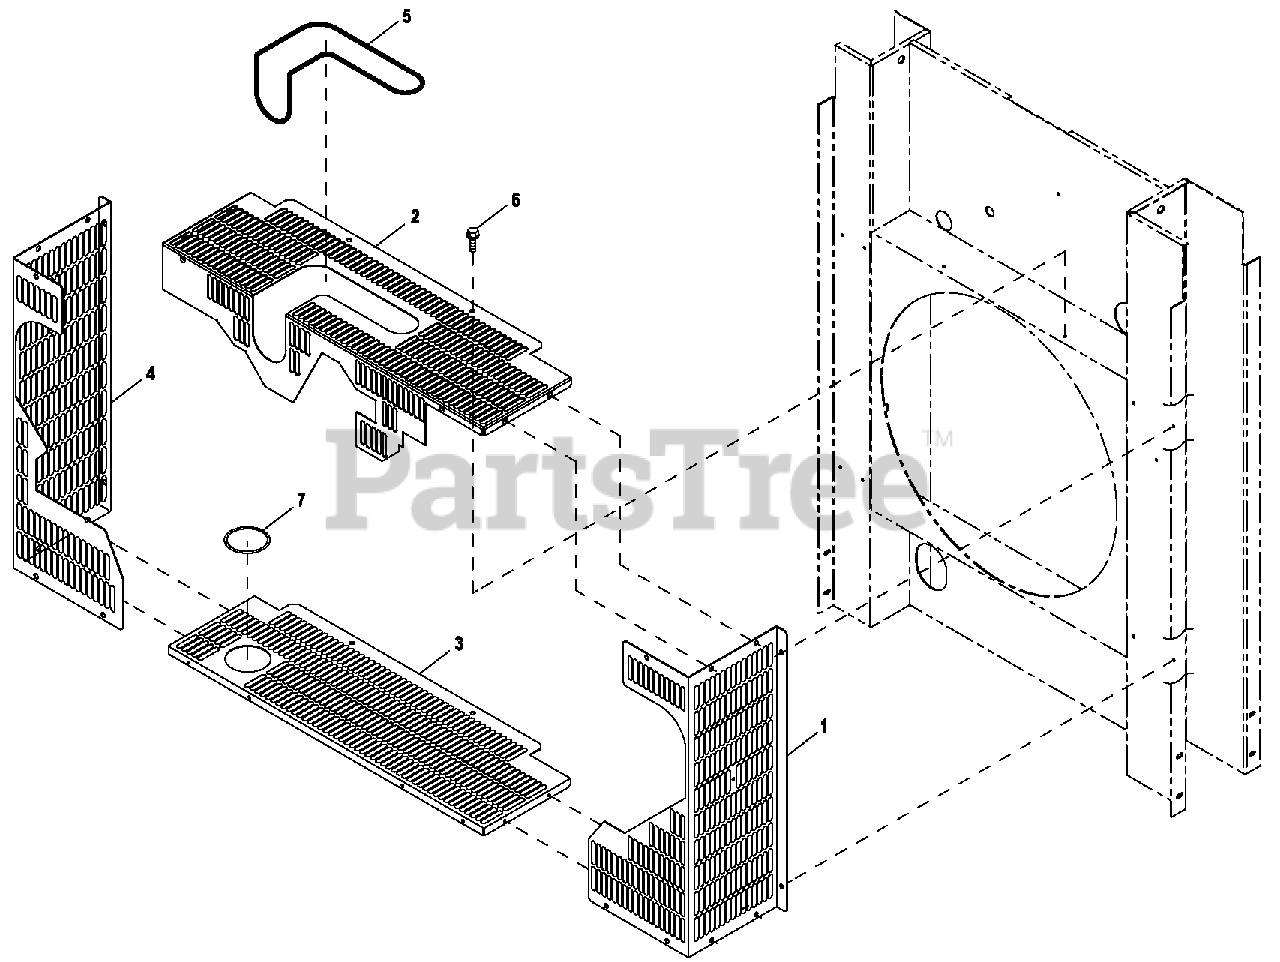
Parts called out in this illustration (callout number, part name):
1	GUARD BELT RIGHT HAND C3
2	BELT TOP C3
3	GUARD BELT BOTTOM C3
4	GUARD BELT LEFT HAND C3
5	TRIM VINYL BLACK 1/8GP (39" LG)
6	SCREW THF M6-1 X 16 N WA Z/JS
7	TRIM VINYL BLACK 1/8GP (10 .37" LG)
